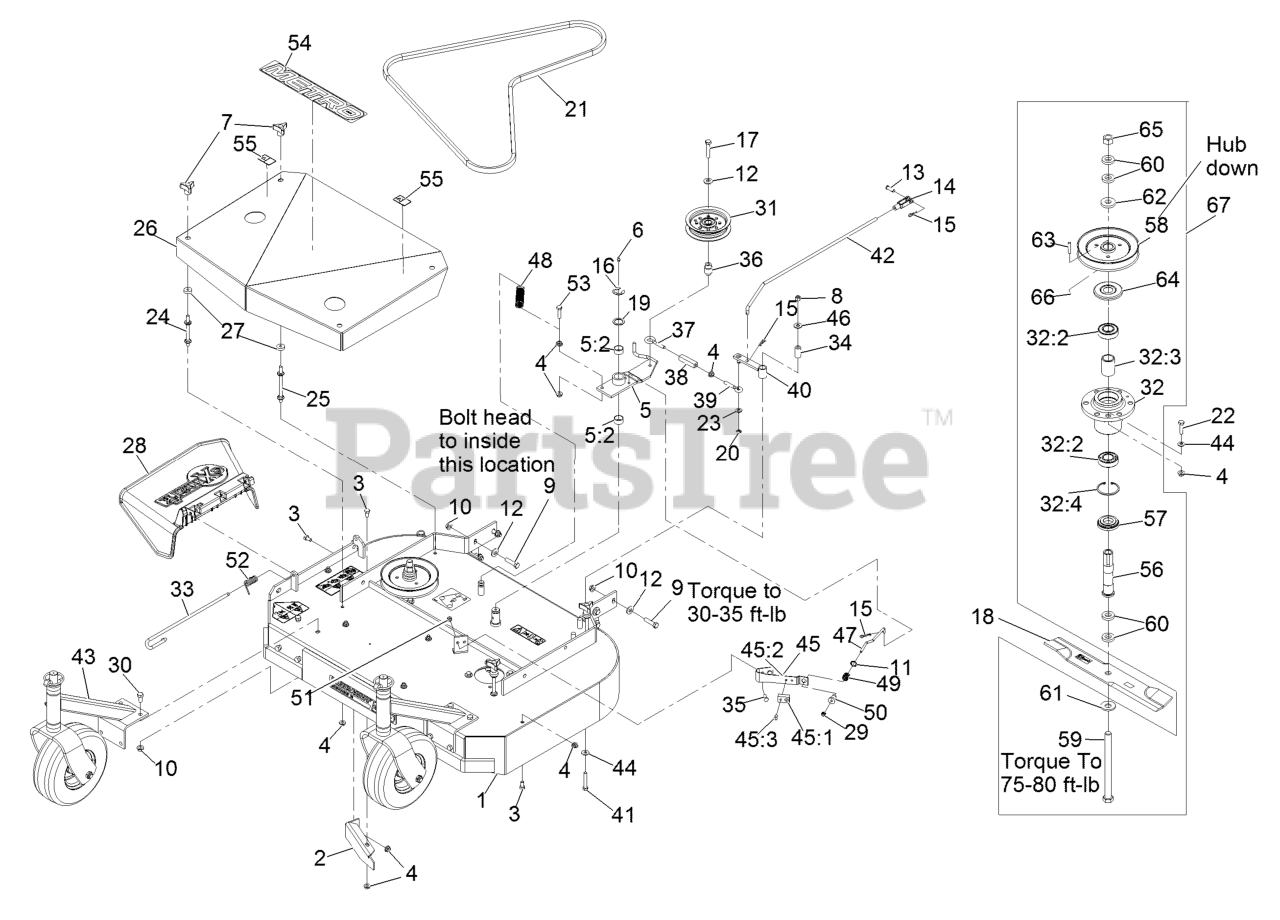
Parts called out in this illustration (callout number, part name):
1	ASM,DECK 36 RIGID
2	BAFFLE-DOGLEG
3	SCREW-HH
5	IDLER ARM ASM
5:2	SLEEVE-BEARING
6	FITTING-GREASE
7	KNOB-3 PRONG
8	NUT-LOCK, NI
9	SCREW-HH
10	NUT-HHF, WHIZ
11	RING-PUSH ON
12	WASHER-BELLEVILLE
13	PIN-CLEVIS
14	YOKE-ADJUSTABLE
15	PIN-COTTER
16	RING-RETAINING, EXT
17	SCREW-HH
19	WASHER-SPINDLE
20	RING-RETAINING, EXT
21	BELT,BLADE METRO 36
22	SCREW-HH
23	WASHER-PLAIN
24	STUD-SHIELD, BELT (SHORT)
25	STUD-SHIELD, BELT (LONG)
26	ASM,SHIELD W/DECALS 36 ME
28	CHUTE DEFLECTOR XRK M056
29	NUT-LOCK, NI
30	SCREW-HH
32	Cutter Housing ASM
32	KIT, CUTTER HOUSING
32:2	BEARING-JACKSHAFT
32:3	SPACER-BEARING
32:4	RING-SNAP
33	PIN-CHUTE
34	TUBE-PIVOT
35	SCREW-HH
36	BUSHING-ENGAGEMENT
37	EYEBOLT-THREAD, LH
38	BODY-TURNBUCKLE
39	EYEBOLT-THREAD, RH
40	ARM-ASSIST, 32/36
41	SCREW-HH
42	ARM-ASSIST, LINKAGE
43	ASM-CASTER MNT W/WEIGHT
44	WASHER-SPRING
45	PAD AND SPRING ASM
45:1	PAD-BRAKE
45:3	RIVET-POP
46	WASHER-FLAT
47	ROD-BRAKE
48	SPRING-EXTENSION
49	SPRING-COMPRESSION
50	SPACER-FLANGED
51	NUT-LOCK, NI
52	SPRING, TORSION
53	SCREW-HH, SPECIAL
54	Decal-Metro
55	DECAL-WARNING
56	TUBE-SPINDLE, SHORT
57	SPACER-GUARD, BOTTOM
58	SHEAVE
59	SCREW-CAP, HH
61	WASHER-SPRING
62	WASHER-RETAINER, SHEAVE
64	GUARD-BEARING, TOP
65	NUT-HEX
66	SETSCREW
67	ASM, CUTTER HOUSING OUTER
